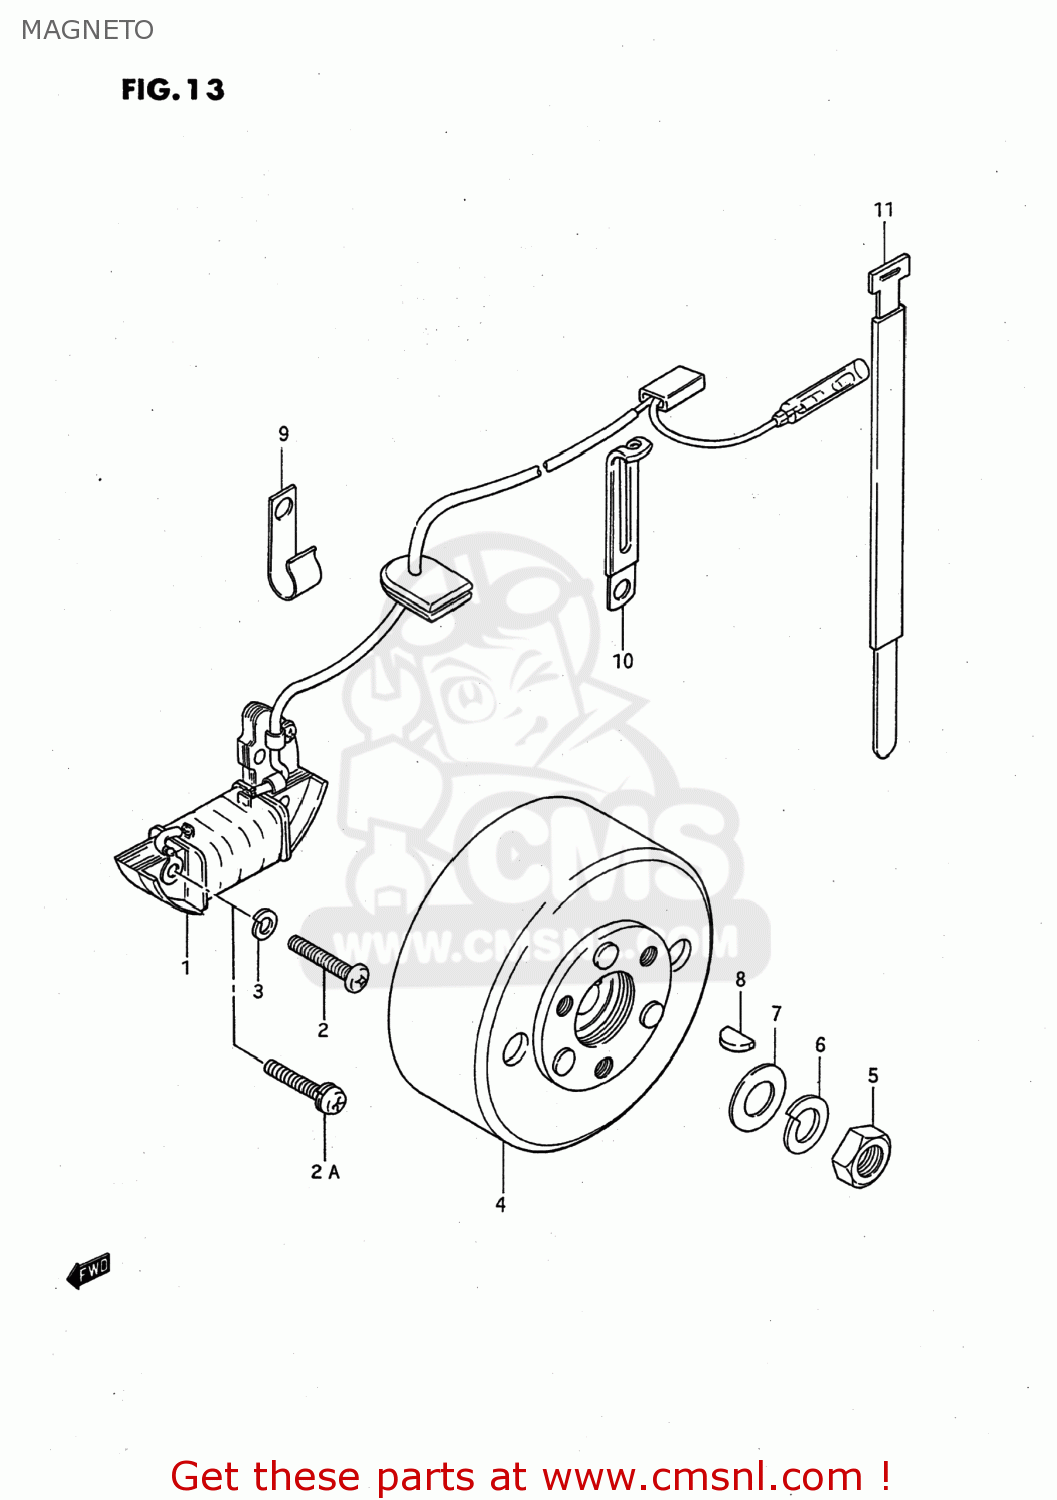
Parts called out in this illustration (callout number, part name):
1	STATOR ASSEMBLY
2	SCREW 4X25
2A	SCREW
3	WASHER,LOCK 4M
4	ROTOR ASSY
5	NUT
6	WASHER
7	WASHER
8	KEY
9	CLAMP
10	CLAMP
11	CLAMP
